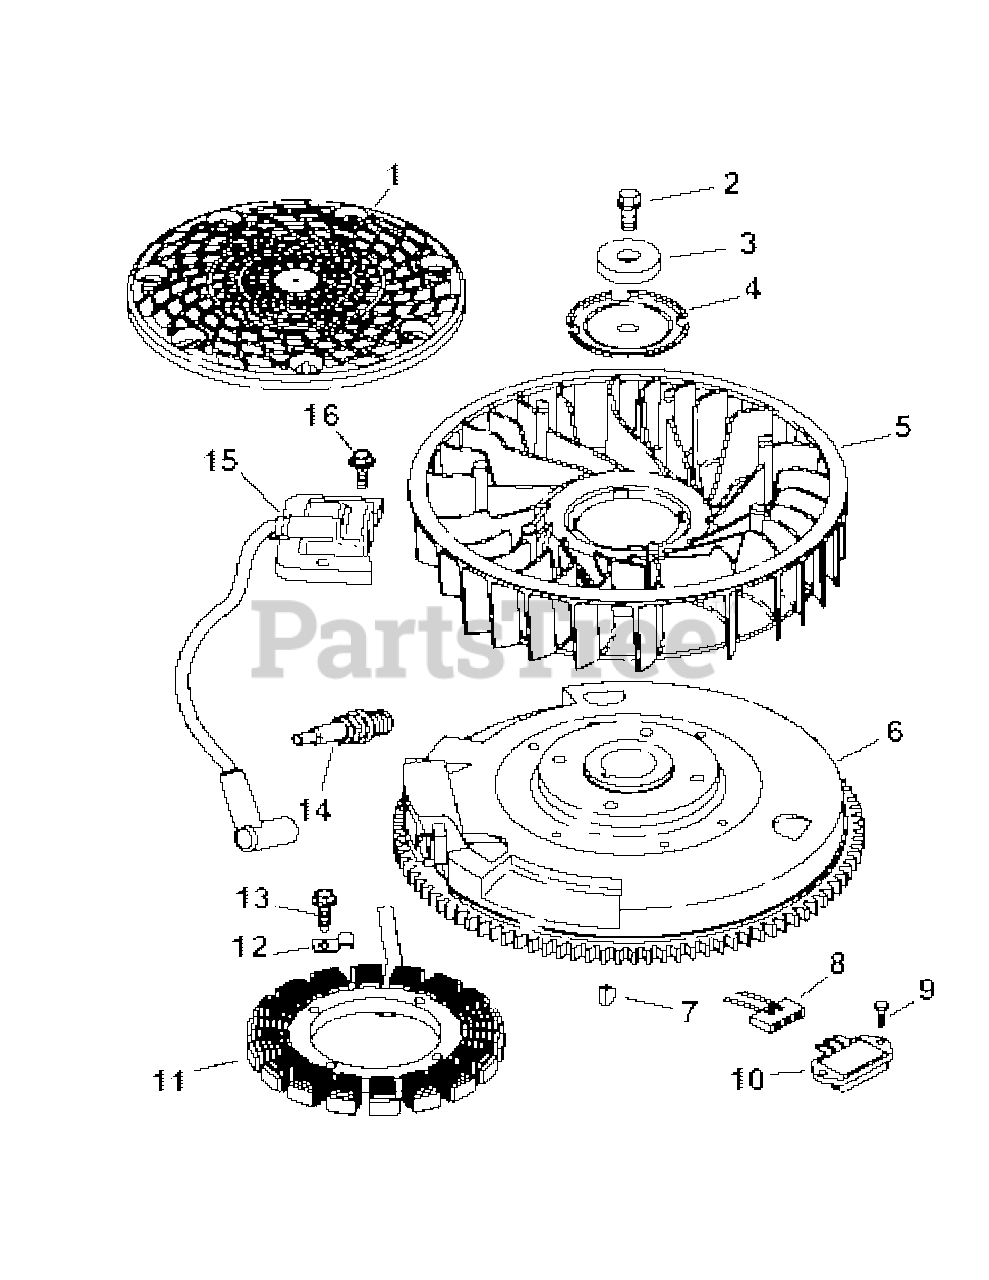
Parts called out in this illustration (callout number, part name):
2	Hex Flange Screw
3	Plain Washer 3/8"
4	Fan Mounting Plate
5	Fan
6	Flywheel
7	Flywheel Key
8	Voltage Regulator
9	Connector
10	Heavy Hex Flange Screw
12	Cable Clip
13	Hex Screw
14	Spark Plug
15	Ignition Module
16	Hex Flange Screw
